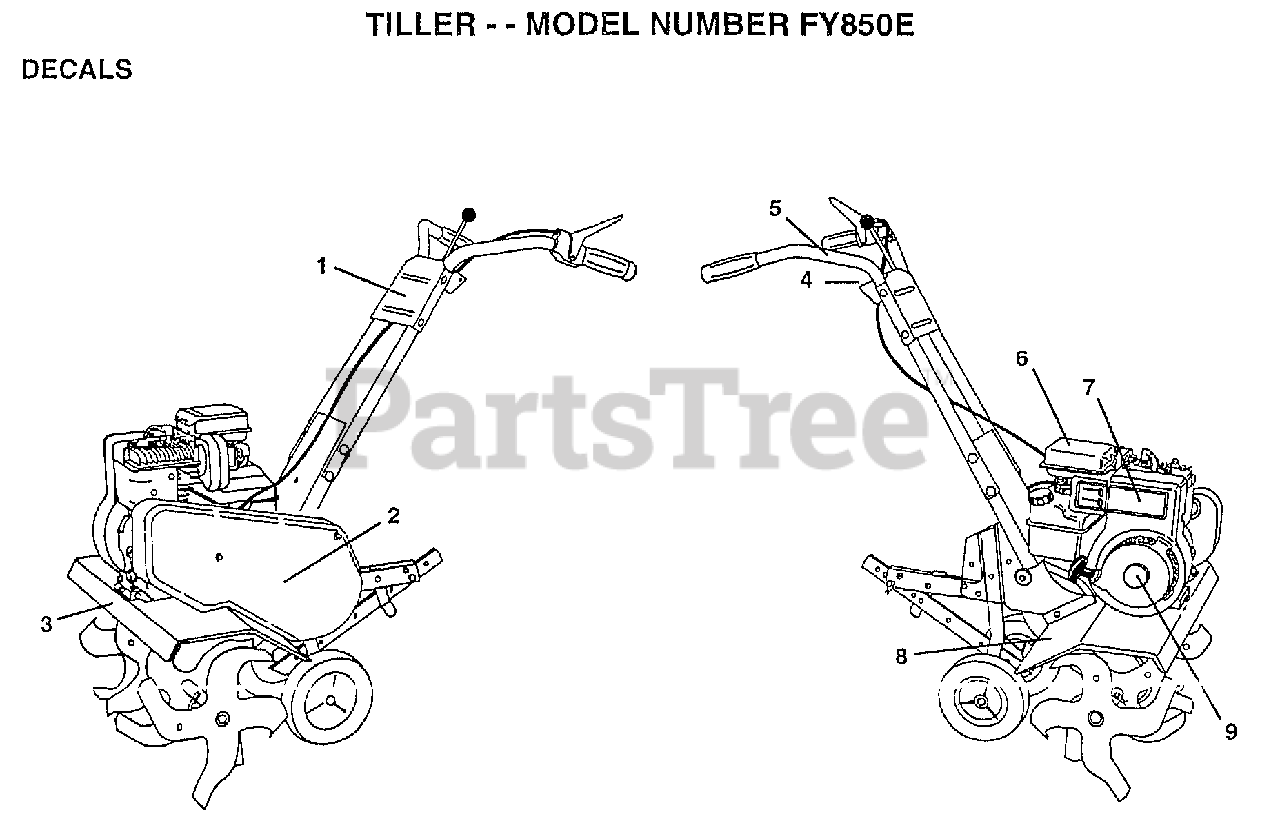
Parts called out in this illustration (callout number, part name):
1	DECAL HANDLE BRKT
2	DECAL.BELT.GUAR
3	DECAL TINE SHIELD
4	DECAL REVERSE
5	DECAL TI
6	DECAL TI
7	DECAL, BRIGGS & STRATTON
9	DECAL, 5 HP
